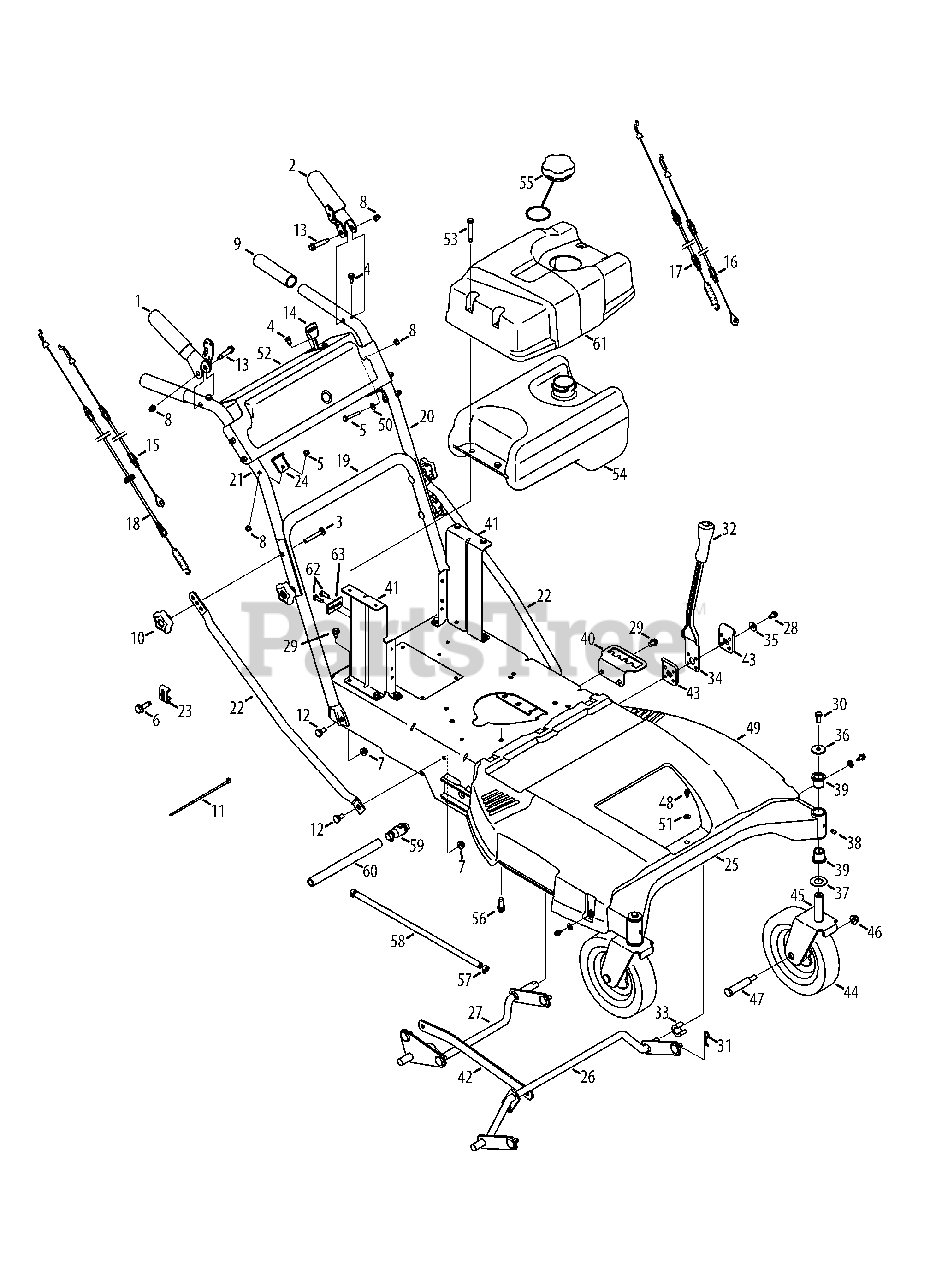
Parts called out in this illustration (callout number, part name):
1	RH Lever Assembly Bracket
2	LH Lever Assembly Bracket
3	Screw, Carriage, 5/16-18 x 2.25
4	Screw, 1/4-20 x 0.500
5	Hex Screw, 1/4-20 x 1.50
6	Screw, #10-32 x 0.625
7	Nut, Flangelock, 5/16-18
8	Lock Nut Cap, 1/4-20
9	Grip, 1.0 ID x 5.0 LG
10	Star Knob, 5/16-18
11	Cable Tie, 3/16 x .05 x 7.4
12	Screw, Shoulder, .435 x .178-5/16 x .56
13	Screw, Shoulder, .375 x 1.355 x 1/4-20
14	Throttle/Choke Cable, 38.0 x 1.1 EXT
15	RH Brake Cable, Tecumseh Trans.
16	LH Brake Cable, Tecumseh Trans.
17	Wheel Clutch Cable
18	Deck Clutch Cable
20	Upper LH Handle
21	Upper RH Handle
22	Adjustable Handle Brace
23	Casing Clamp
24	RH Cable Mount Bracket
24	LH Cable Mount Bracket
25	Frame Assembly
26	Front Deck Lift Assembly
27	Rear Deck Lift Assembly
28	Hex Screw, 5/16-18 x .50
29	Screw, 5/16-18 x 0.625
30	Hex Screw, 5/16-24 x .750
31	Click Pin, .092 x 1.64 LG
32	Grip Handle, 1/2
33	Plastic Spacer, .63 ID x .75 LG
34	Deck Height Lever
35	Washer, Bell, .340 x .872 x .060
36	Washer, Flat, .330 x 1.25 x .120
37	Washer, Flat, .760 ID x 1.50 OD
38	Drive Lube Fitting, 3/16
39	Flange Bearing, .760 x .941 x 1.0
40	Height Adjustment Bracket
41	Fuel Tank Mount Bracket
42	Link Pivot Bracket
43	Lever Pivot Bracket
44	Caster, Wheel, 8 x 1.75
44	Bearing, Flange w/ftg
45	Wheel Caster Bracket
46	Nut, Flangelock, 3/8-16
47	Bolt, Shoulder, .625 x 2.515 x 3/8-16
48	Screw, 1/4-14 x 0.625
49	Belt Cover
50	Washer, Bell, .265 x .75 x .062
51	Washer, Flat, .25 x .630 x .0515
53	Screw, Shoulder, .3175 x .188, 1/4-20
54	Fuel Tank
56	Screw, 3/8-16 x 1.250
57	Hose Clamp, .490 DIA.
58	Fuel Hose, Low Permeation, 1/4
60	Extension Hose
61	Fuel Tank Cover
62	Screw, 1/4-20 x 0.750
63	Plate, Shift
